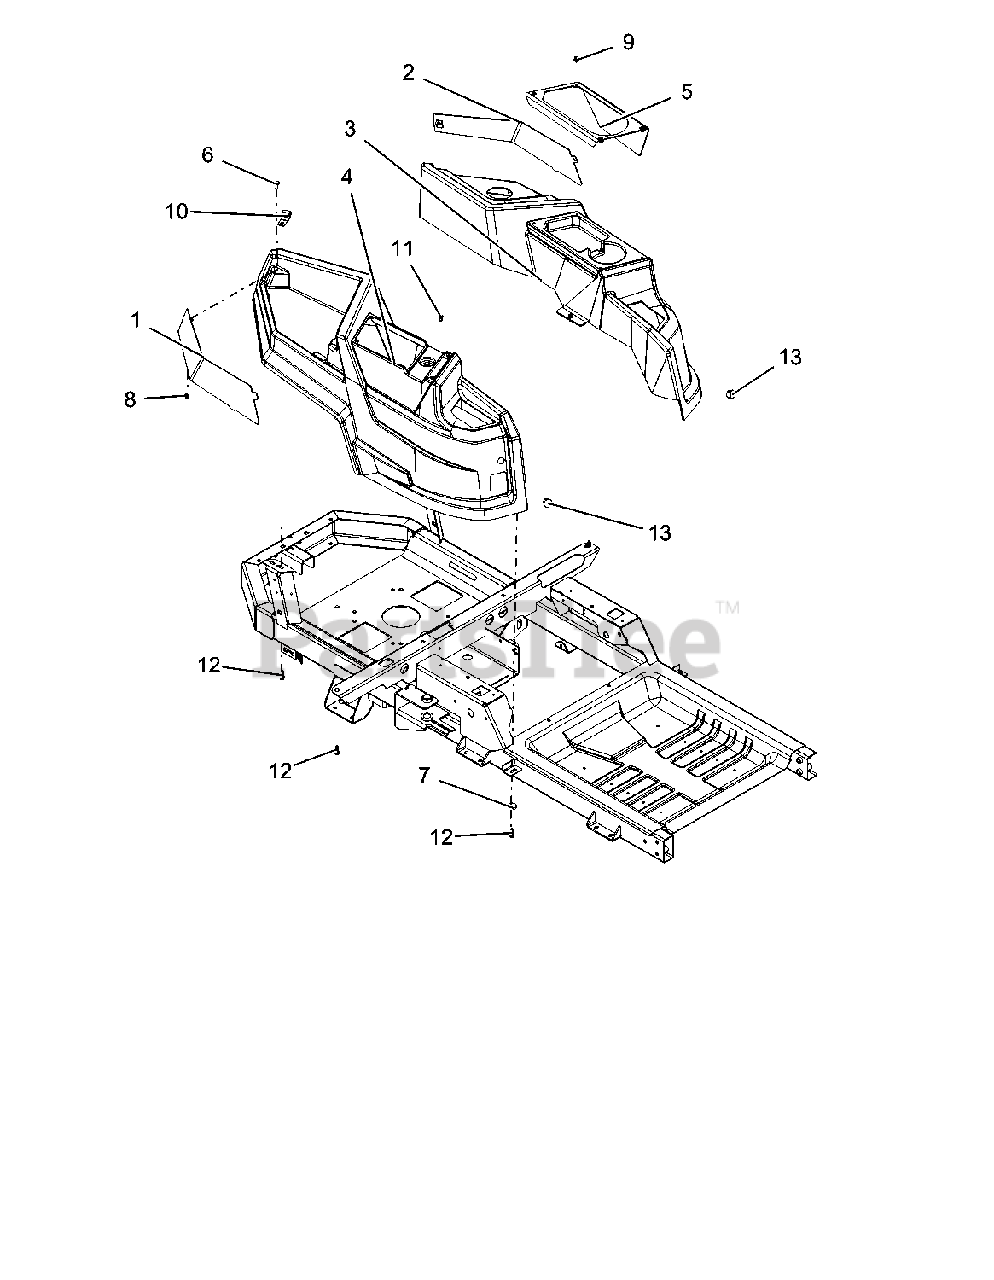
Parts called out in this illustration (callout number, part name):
1	WLMT, FENDER BLOCKOFF-RH
2	WLMT, FENDER BLOCKOFF-LH
3	FENDER, LH -ZOOM
4	FENDER, RH -ZOOM
5	PANEL, CUPHOLDER/STORAGE (LH)
6	BLT-HEX.25-20X.62 BLKZC ROHS
7	WSHR-FL-STL .406X1.00X.188 YWZ
8	@NUT-LK-TOP-FLG .25-20 YWZC
9	RIVET, PLASTIC .195 DIA.
10	J-CLAMP
11	SCR-TAP .25-20X.50 HWH TR YWZ
12	SCR-.312X.75 #14H H/W/H H/L CZ
13	PLUG, HOLE .75 (BLACK)
